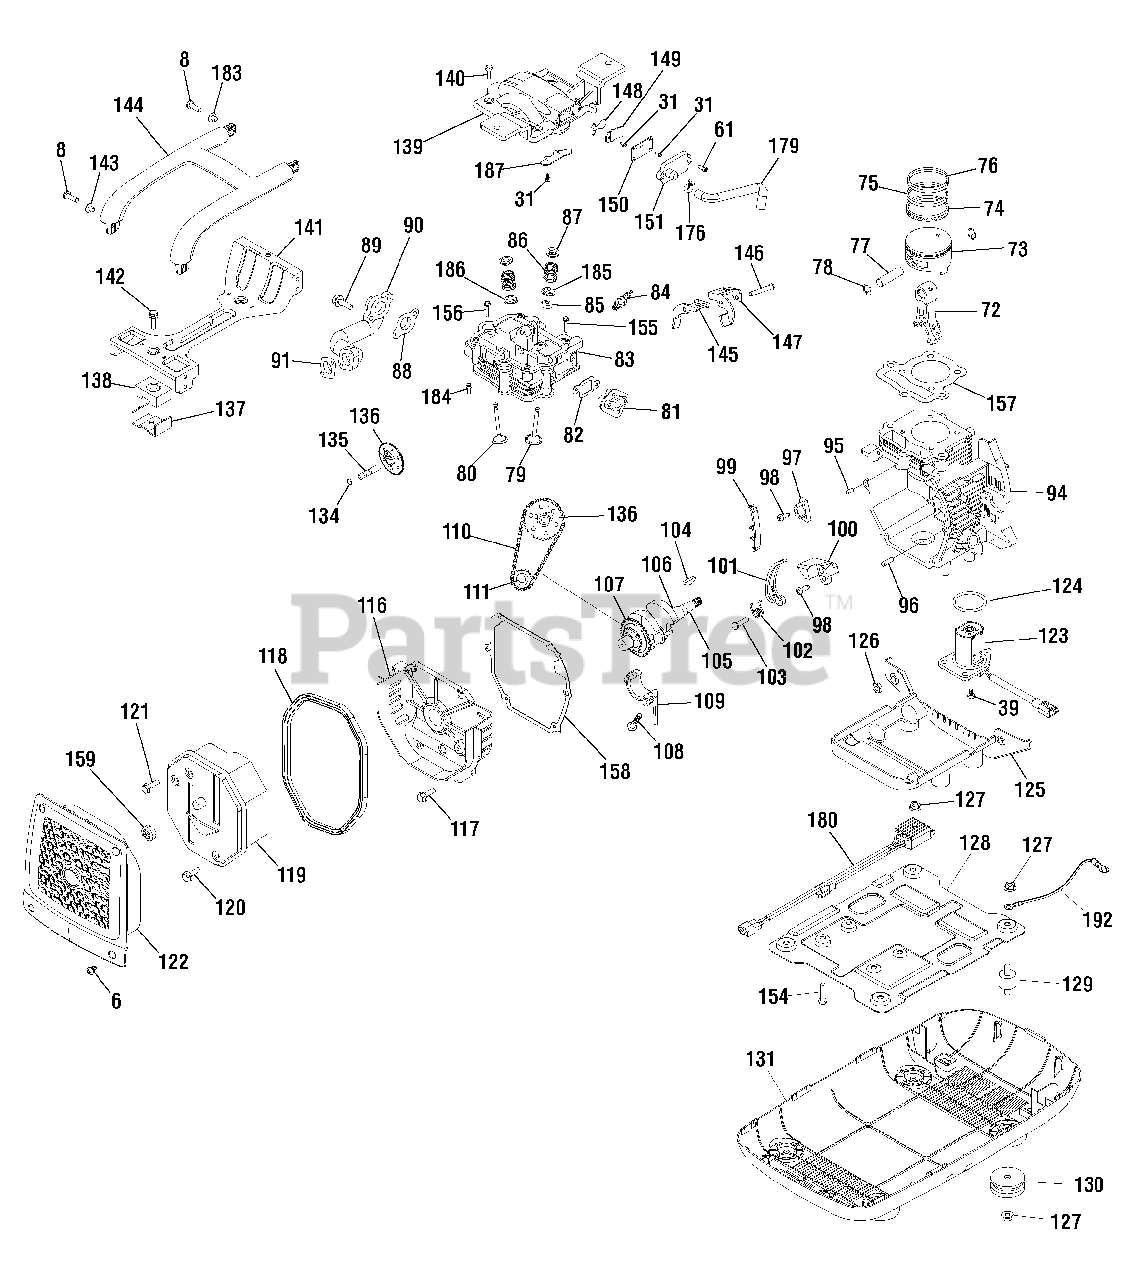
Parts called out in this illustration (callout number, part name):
31	BOLT
61	SCREW
72	ROD
73	PISTON
74	RING
75	RING
76	RING
77	PIN
78	RETAINER-PIN
79	VALVE-INTAKE
80	VALVE-EXHAUST
83	CYLINDER HEAD
85	SEAL-VALVE OIL
86	SPRING
87	SEAT-VALVE
89	BOLT
90	MUFFLER
94	CRANKCASE
95	PIN
96	PIN
97	BLOCK
98	SCREW
99	BRACKET
100	BRACKET
101	ARM-TENSION
102	SPRING
103	PIN
104	KEY
105	CRANKSHAFT
106	BEARING
107	GEAR
108	BOLT
109	COVER
110	CHAIN
111	WHEEL-CHAIN
116	COVER-CRANKCASE
117	BOLT
118	BLOCK-RUBBER
119	MUFFLER
120	BOLT
121	BOLT
125	COVER
126	NUT
129	MOUNT-VIBRATION
130	MOUNT-VIBRATION
134	O-RING
135	SHAFT
136	CAM-ASSEMBLY
137	BRACKET
138	MOUNT-VIBRATION
140	BOLT
141	BRACKET
142	BOLT
145	ARM-EXHAUST VALVE
146	PIN
147	ARM-INTAKE VALVE
150	BOARD-VALVE
151	BOARD-VALVE
154	BOLT
155	BOLT
156	BOLT
157	GASKET
158	GASKET-CRANKCASE
176	CLAMP
180	REGULATOR-VOLTAGE
184	BOLT
185	SEAT
186	SEAT
187	PLATE
